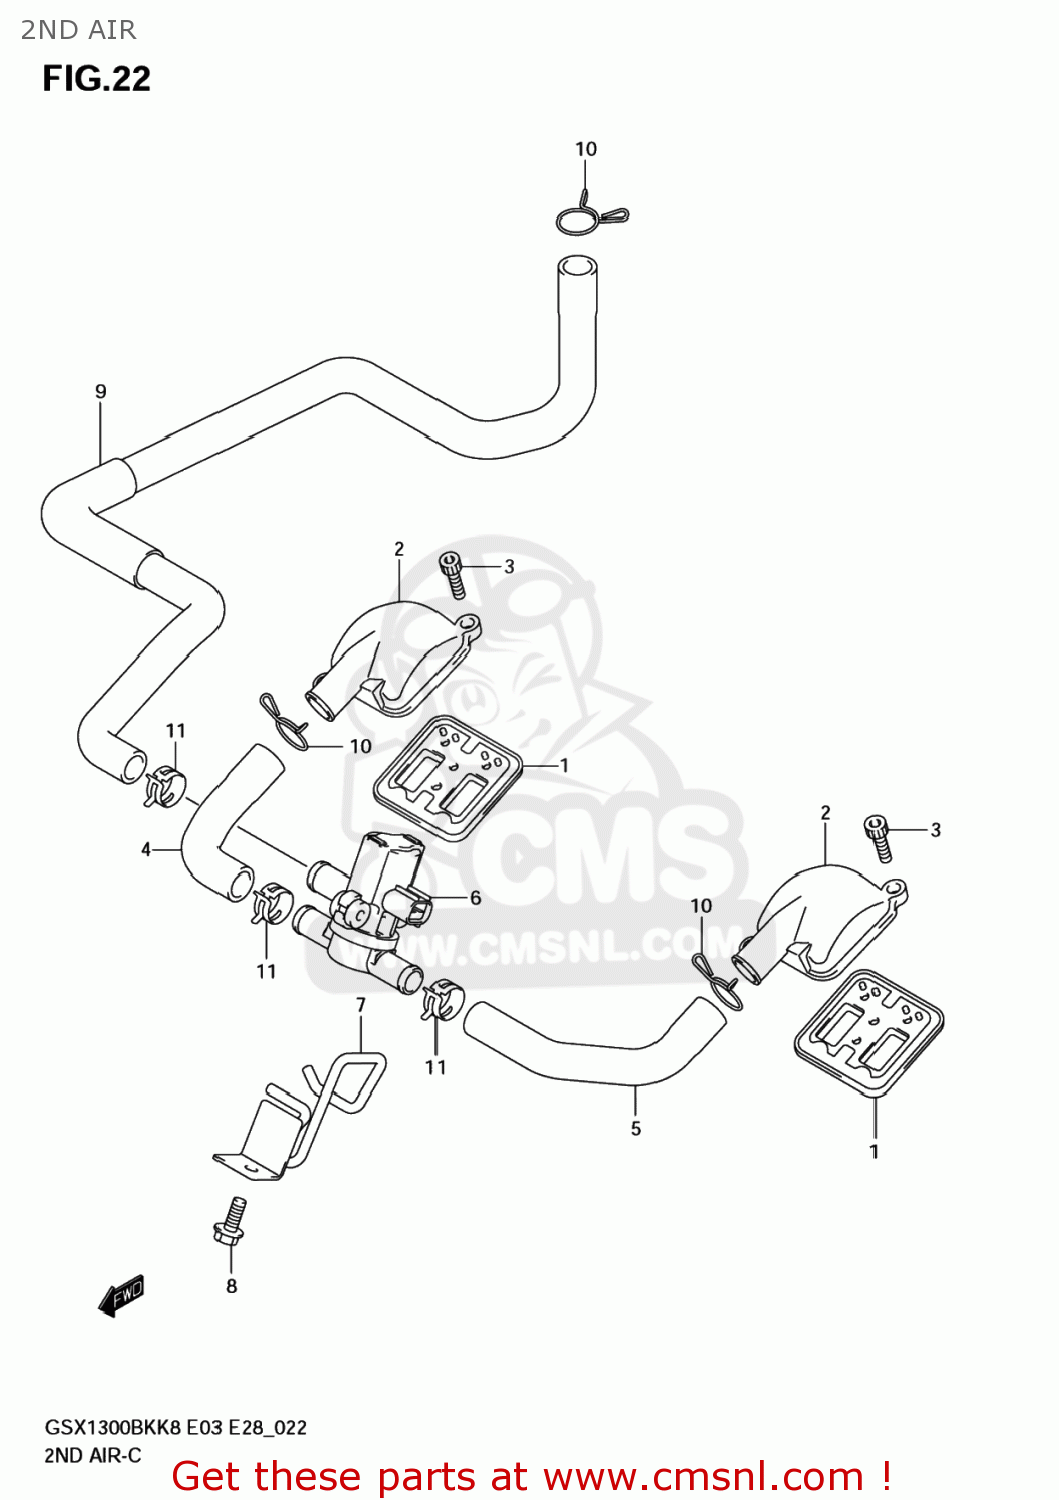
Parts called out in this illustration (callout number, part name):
1	VALVE ASSY,2ND AIR REED
2	COVER,2ND AIR REED VALVE
3	BOLT(6X16)
4	HOSE,2ND AIR VALVE,R
5	HOSE,2ND AIR VALVE,L
6	VALVE ASSY,AIR CUT
7	BRACKET,2ND AIR VALVE
8	BOLT(6X16)
9	HOSE,2ND AIR CLEANER
10	CLIP
11	CLIP
